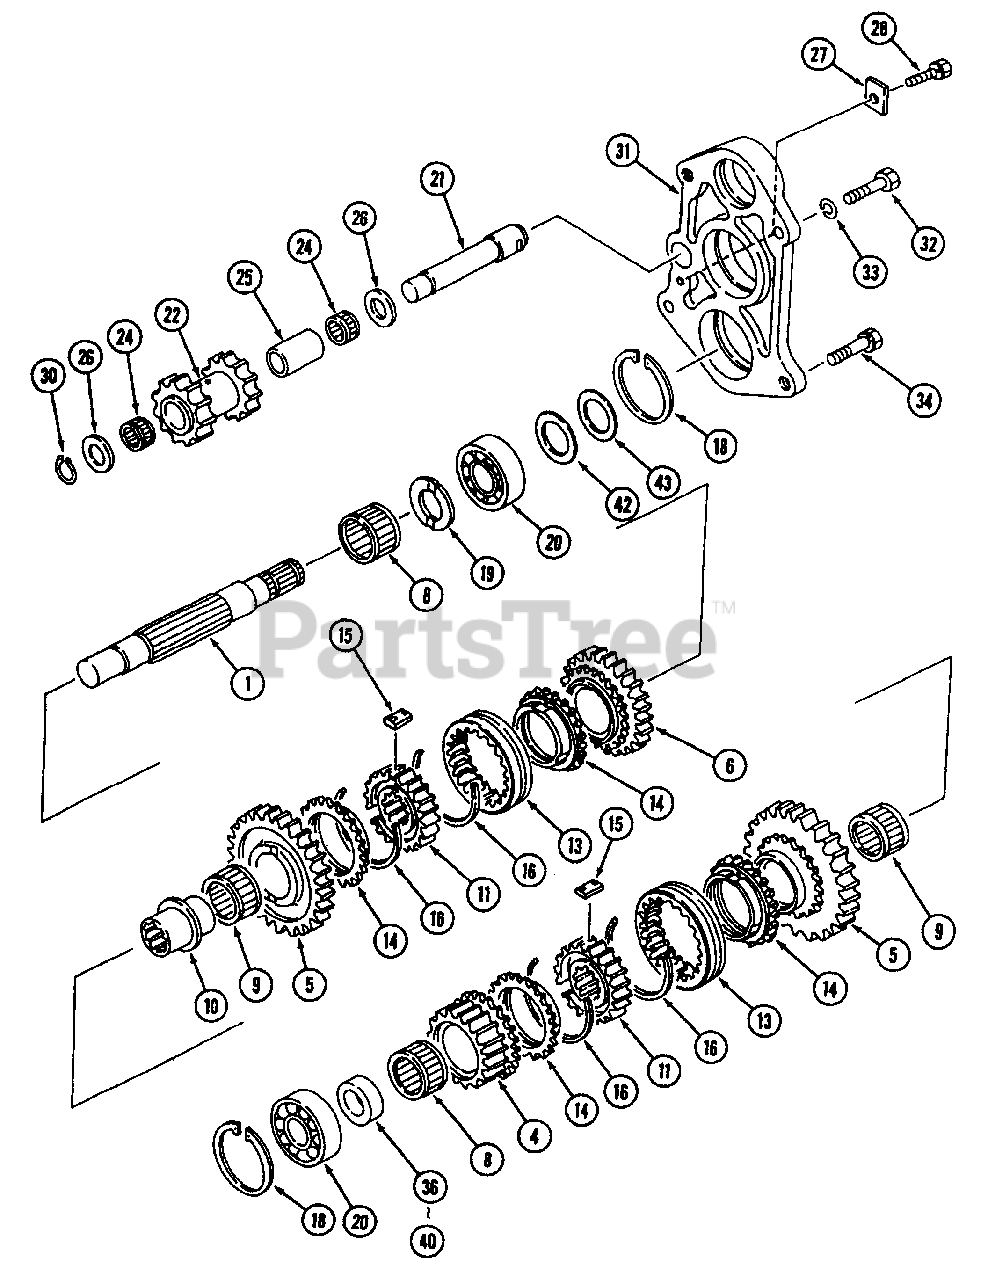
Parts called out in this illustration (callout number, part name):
1	Shaft, Main Change
21	Shaft, Reverse
36	Collar
37	Collar
38	Collar
39	Collar
40	Collar
